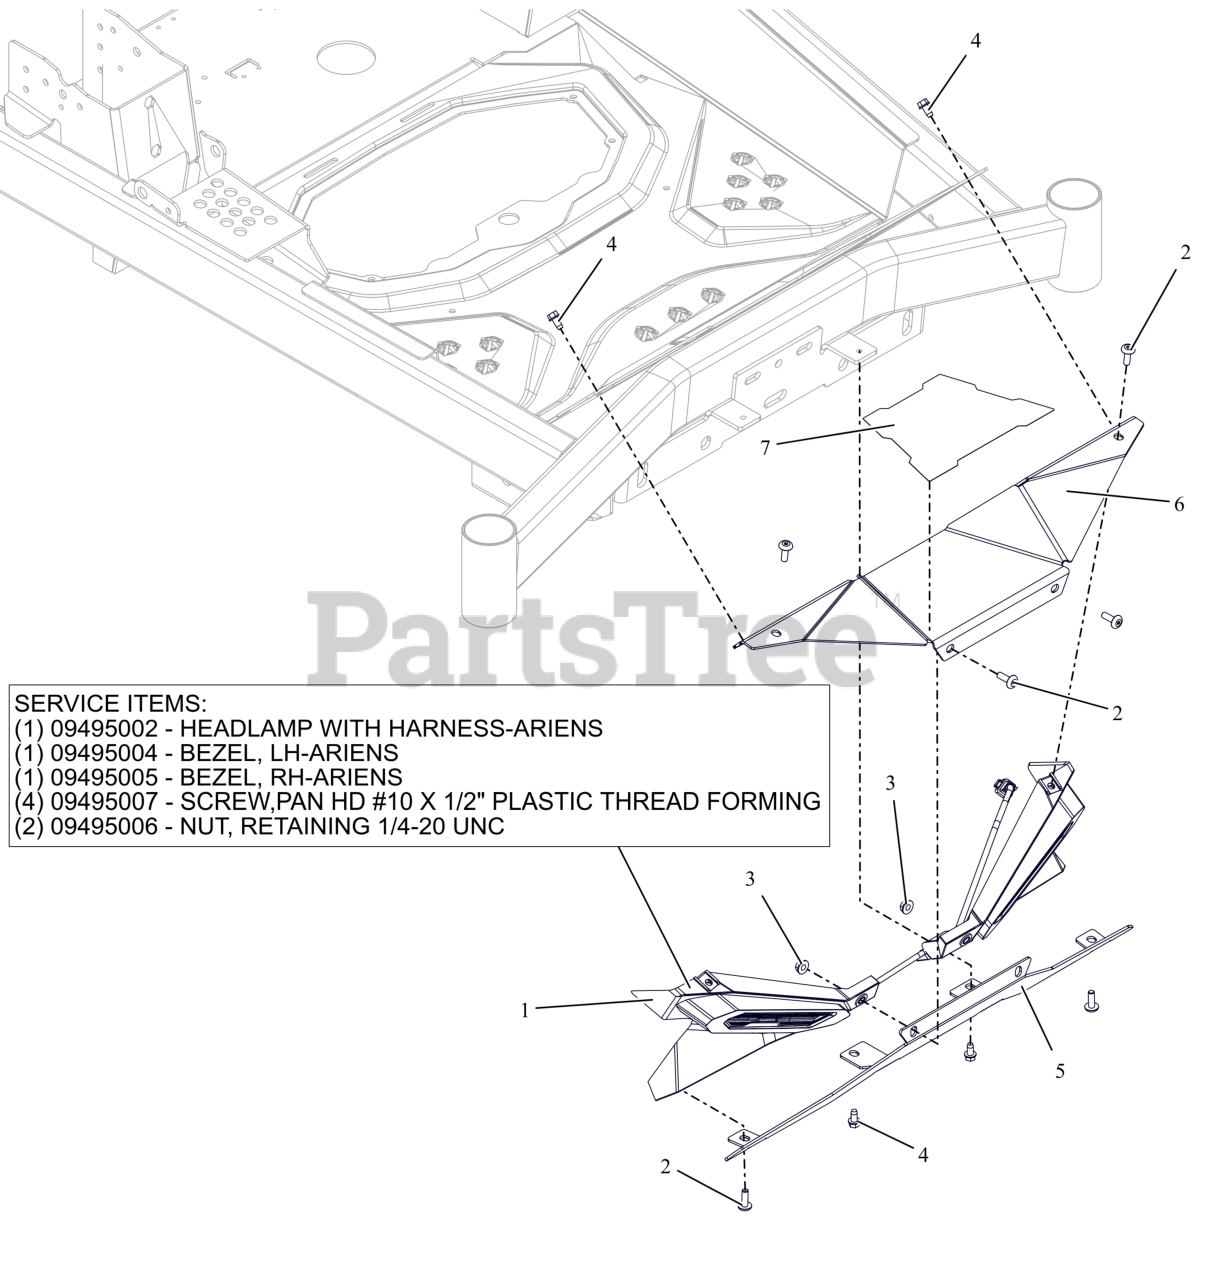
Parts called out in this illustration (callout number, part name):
1	LIGHT ASSY- HEADLIGHT-ARIENS
1	HEADLAMP- WITH HARNESS-ARIENS
1	BEZEL- ARIENS LH
1	BEZEL- ARIENS RH
1	SCR-.250-20 PAN HEAD-BSP210008
1	NUT- RETAINER .250-20 BLZINC
2	SCR-MCH .25-20X.75 TXTR ZB500
3	NUT-LK-CTR-FLG .25-20 ZC120
4	SCR-TAP .25X.50 HWH ZB500
5	PLATE, LOWER BEZEL MTG-ARIENS (BLACK)
6	FOOTREST, FRONT - ARIENS (BLACK)
7	GRIP- TAPE-FRONT STEP-ARIENS
